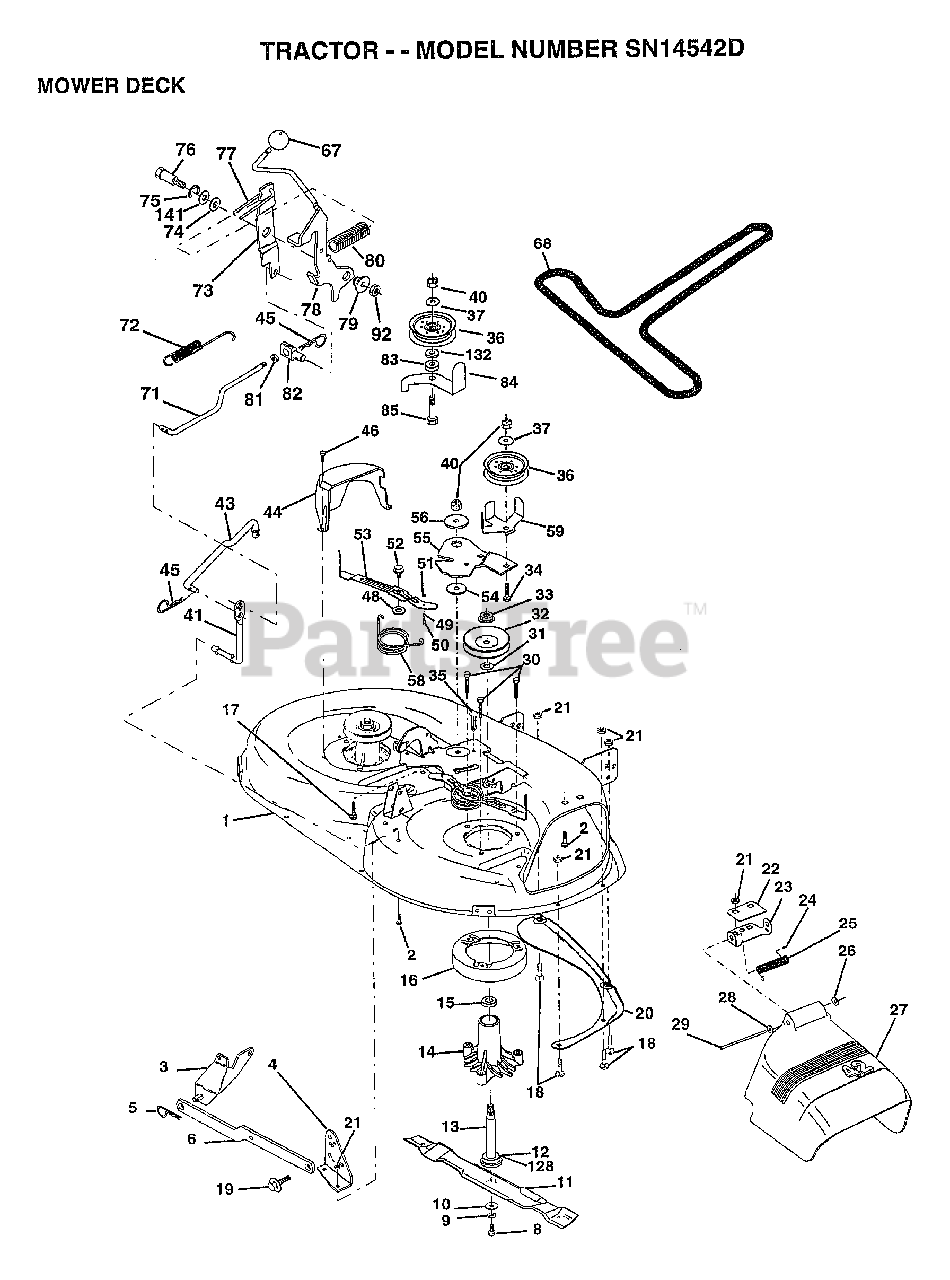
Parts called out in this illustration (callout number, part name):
1	"HOUSING ASSY.42"""
2	BOLT
3	BRKT ASM SWAY BAR
4	BRKT DECK SW BAR
8	BLADE BOLT
10	WASHER.HARD.BLADE
11	"BLADE.42"" HIPERF"
12	BEARING.BALL
14	HSG ASM MANDREL
15	BEARING
16	STRIPPER RND MWR
17	BOLT RDHD 3/8-16
18	BOLT
19	BOLT SHD 5/16-18
20	BAFFLE VORTEX 42
22	STIFFENER BRKT
23	DEFLECTOR BRKT
24	CAP-SLEEVE LT
24	NUT PUSH M
25	SPRING TORSION
27	DEFLECTOR.SHIELD
28	WASHER
29	HINGE ROD
30	"SCREW-THD ROLL,WA"
31	WASHER
32	PULLEY.MANDREL.42
34	BOLT
35	XMAS TREE FASTNER
36	FLAT IDLER PULLEY
37	WASHER
41	PIVOT ROD
43	ROD CLUTCH W/NIBS
44	GUARD MAND LH BLK
45	RETAINER M
46	SCREW.1/4-20X5/8
48	HARD SMALL WASHER
49	ROLLER ASM-CAM
50	SHOULDER BOLT
51	LOCKNUT
52	BOLT.SHLD.5/16-18
53	BRAKE PAD ARM ASM
54	HARDENED WASHER
55	ARM-IDLER
56	SPACER RETAINER
58	SPRING TORSN BRAK
59	GUARD IDLER TUV
67	KNOB.RD.7/16-14
68	BELT.V.T-PATH
71	ROD CLUTCH 38/42
72	RETURN SPRING
73	CLUTCH ARM SECOND
74	WASHER
75	RING
76	SHOULDER BOLT
77	SPRING KEEPER
78	LEVER.ASM.CLUTCH
79	BUSHING
80	SPRING.CLUTCH.MWR
81	NUT
82	TRUNION ADJ
83	WASHER
84	"KEEPER-BELT,FIXED"
85	BOLT
92	NUT
128	WASHER.FELT.
132	WASHER GT
141	WASHER .T
